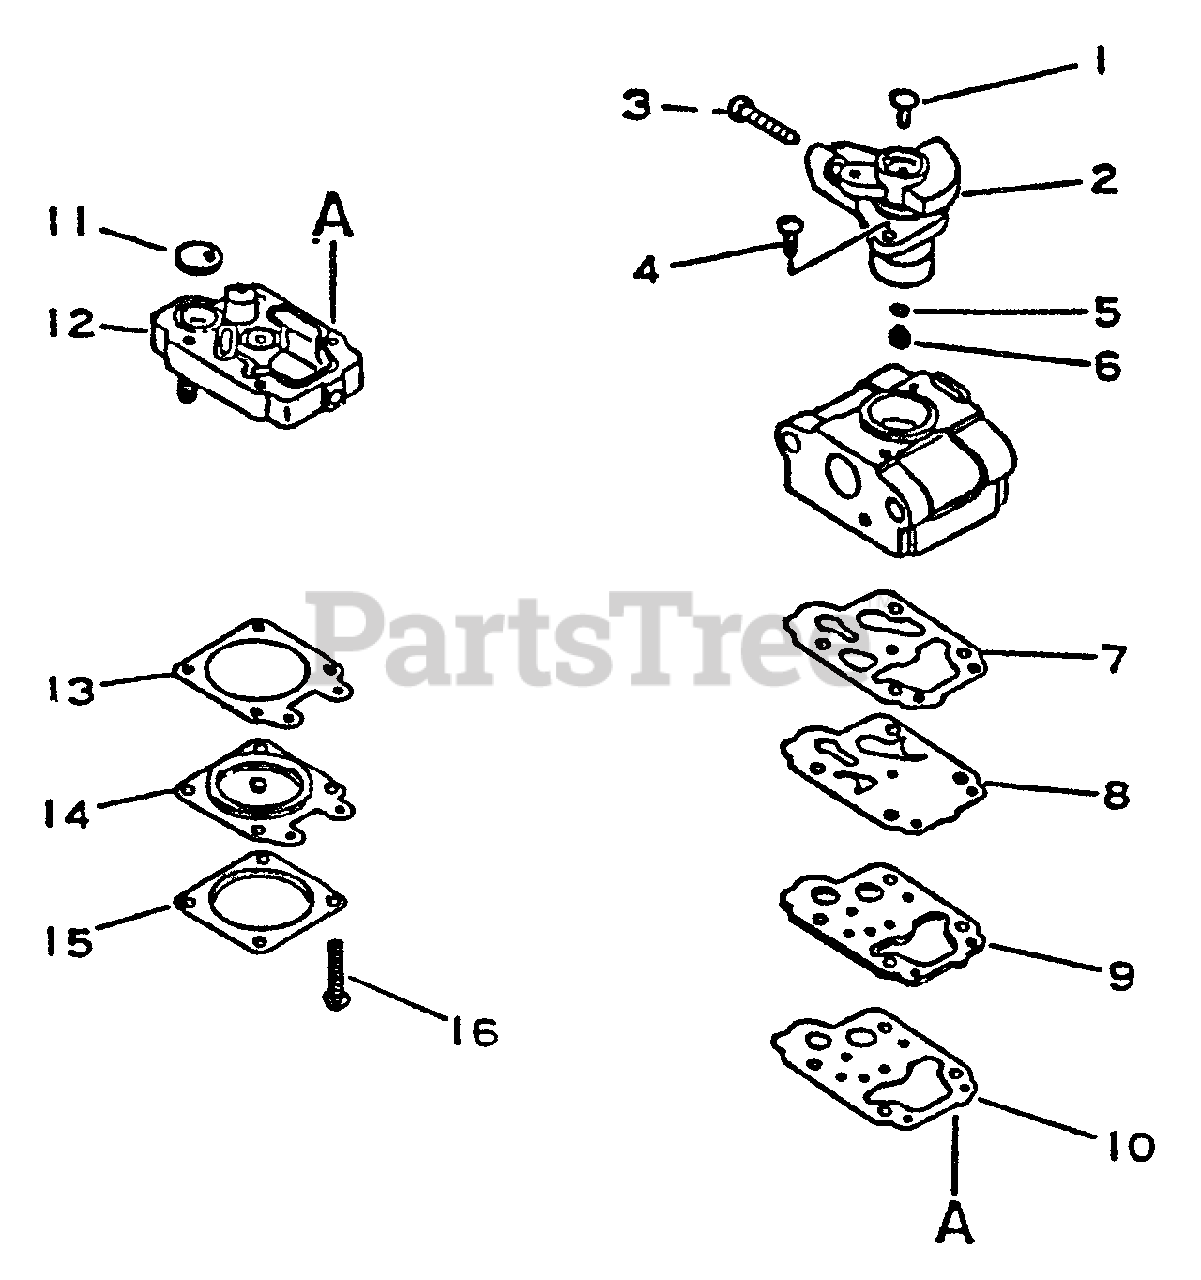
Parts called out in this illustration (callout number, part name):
2	VALVE ASSY, THROTTLE
4	SCREW, THROTTLE COLLAR
5	O-RING
6	JET
9	COVER, PUMP
10	GASKET, PLATE
11	STRAINER
12	BASE, PURGE
13	GASKET, METERING
14	DIAPHRAGM, METERING
15	COVER, METERING DIAPHRAGM
